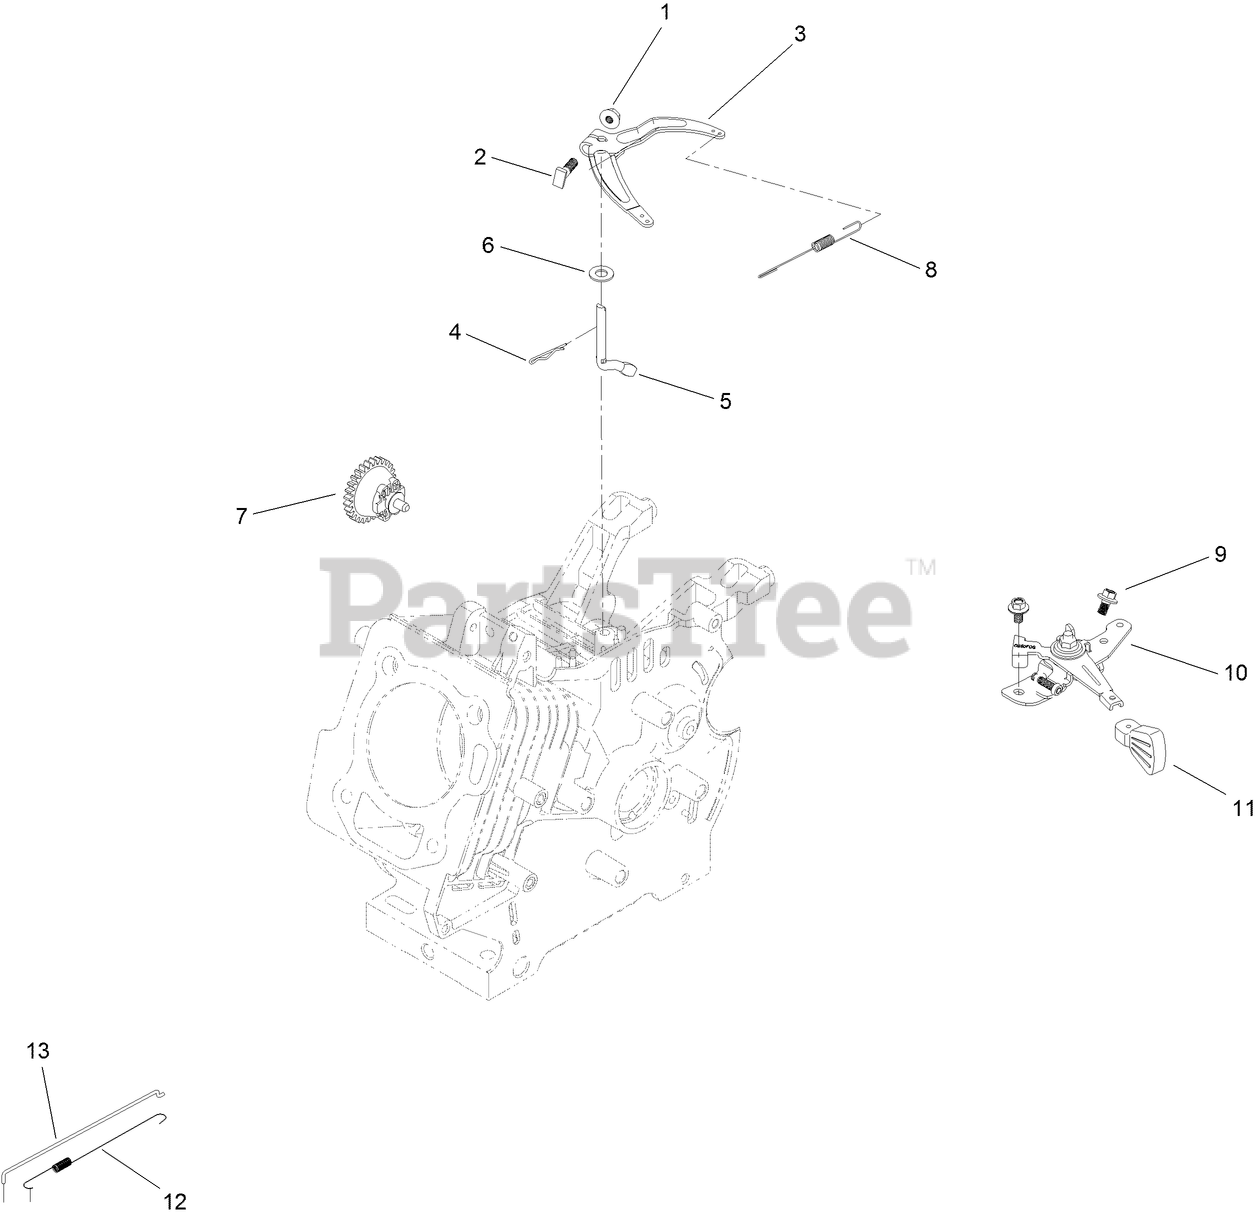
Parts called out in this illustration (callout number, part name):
1	NUT-FLANGE
2	BOLT-ARM, GOVERNOR
3	ARM-GOVERNOR
4	PIN-HAIR
5	SHAFT-GOVERNOR
6	WASHER-PLAIN
7	GOVERNOR GEAR ASM
8	SPRING-GOVERNOR
9	SCREW-HHF
10	THROTTLE CONTROL ASM
11	KNOB-CONTROL, THROTTLE
12	SPRING-RETURN, THROTTLE
13	ROD-GOVERNOR
